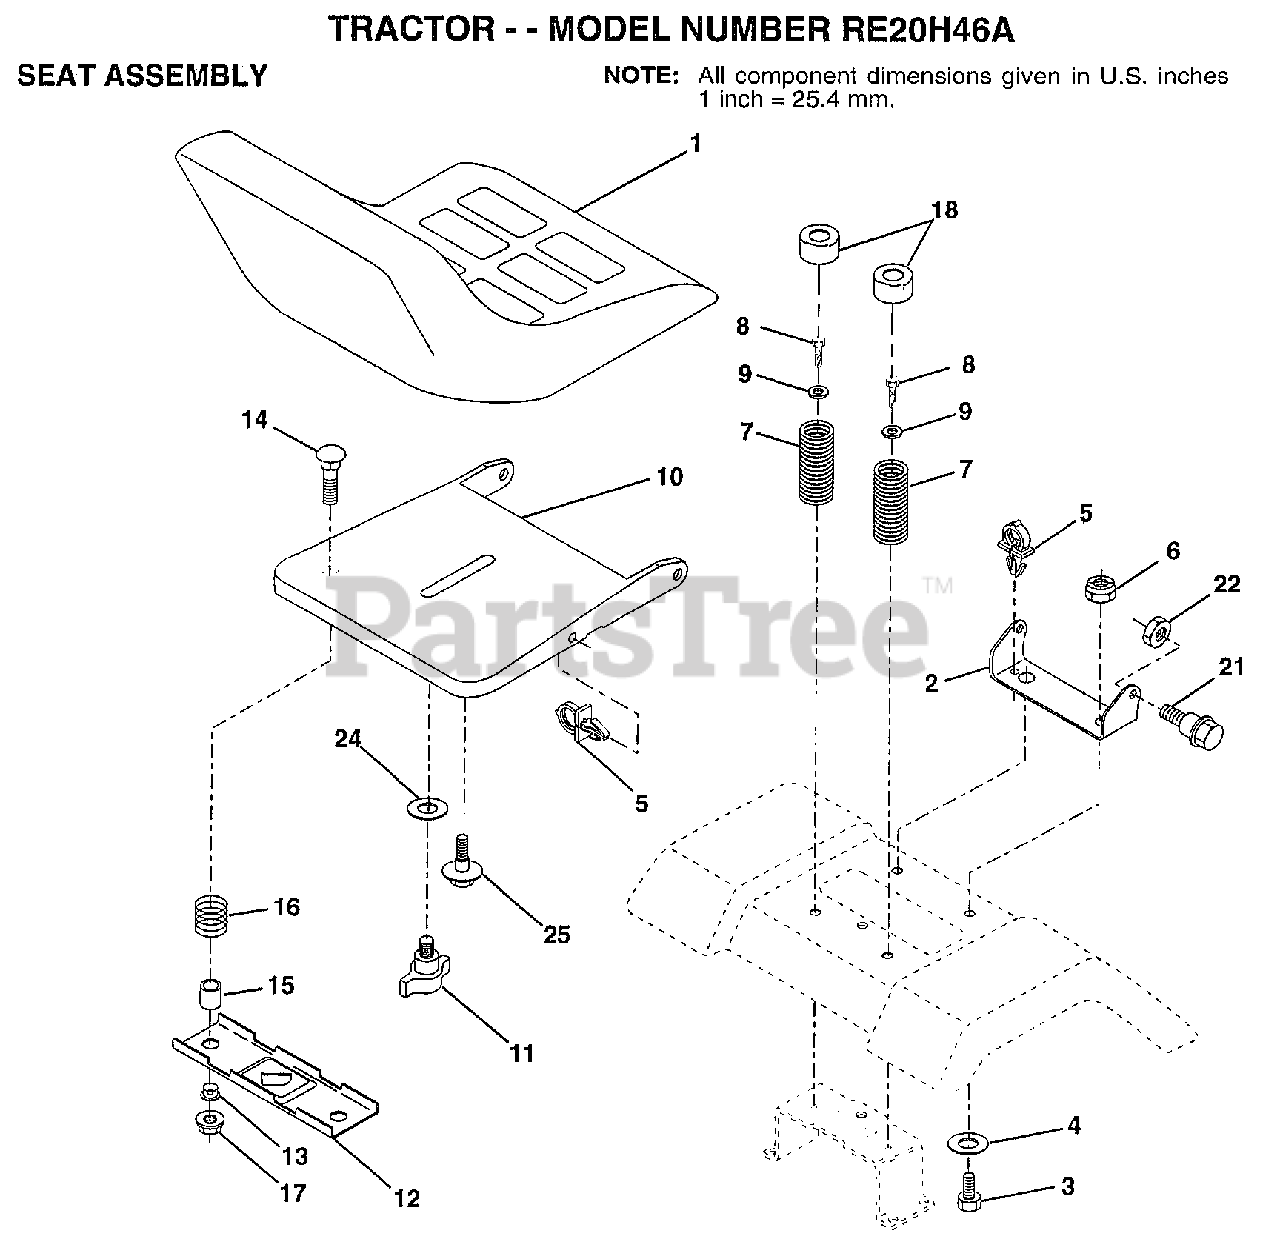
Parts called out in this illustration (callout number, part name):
2	BRACKET PVT SEAT
5	CLIP.PUSH-IN.HING
6	NUT
7	SPRING COMPRESSIO
10	PAN-SEAT
11	KNOB.SEAT.ADJ.WINGNUT
12	BRKT SWITCH
13	BUSHING
14	BOLT-RD HD SQ NK
15	SPACER SPLIT
16	SPRING COMPRESSED
18	CAP SPRING
21	"BOLT,SHOULDER"
22	NUT
24	WASHER
25	"BOLT,SHOULDER"
27	SCREW LT
28	BOLT.5/16-18.UNC
